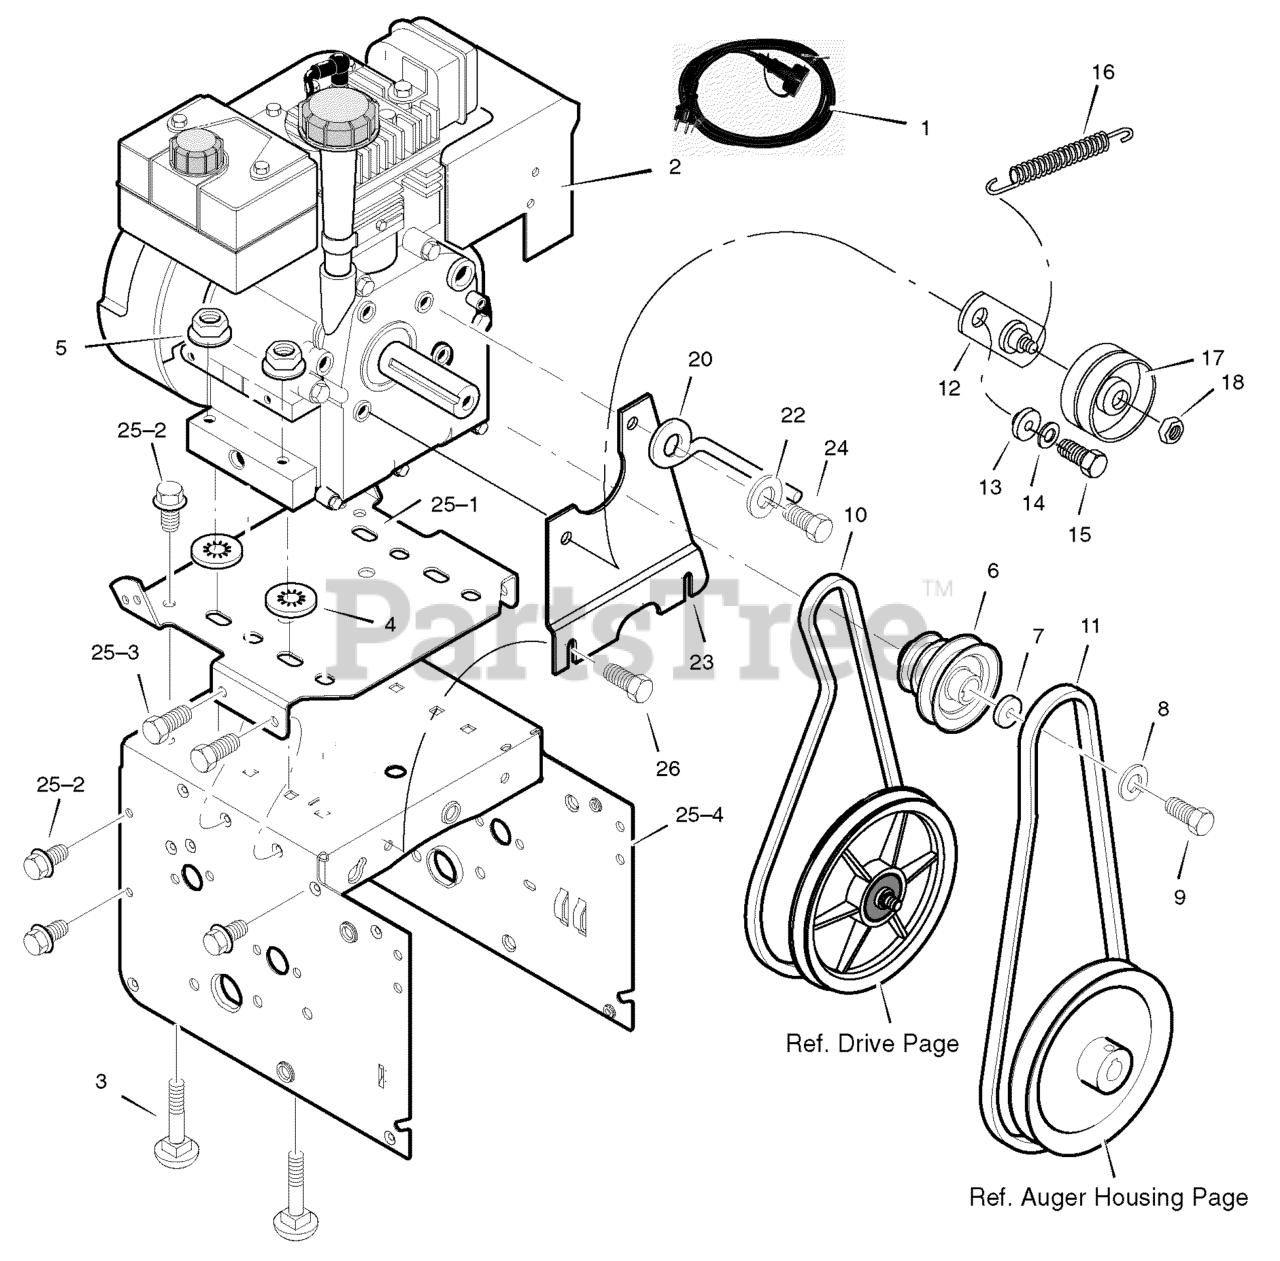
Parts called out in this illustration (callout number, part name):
1	CORD, STARTER
2	ENGINE *
3	BOLT, CARRIAGE 5/16-18
4	RETAINER, PUSH
5	NUT, HEX 5/16-18
6	PULLEY, ENGINE
7	WASHER
8	WASHER .38ID
9	SCREW, 3/8-24 x 1.00
10	BELT, DRIVE V 3L
11	BELT, AUGER V 4L
12	BRACKET ASSEMBLY, IDLER
13	BUSHING, IDLER BRACKET
14	WASHER, SPLIT
15	SCREW 5/16-24 X 1.00
16	SPRING, IDLER TRACTION DRIVE
17	PULLEY, IDLER
18	NUT, JAM 3/8-16
20	GUIDE, BELT
22	WASHER, SPTLK .31X.58X.08
23	PLATE, ANTI VIBRATION
24	SCREW, 5/16-24X 1.00
25	FRAME ASSEMBLY
25-1	PLATE, ENGINE MOUNT
25-2	SCREW, TAP 1/4-20 X .63
25-3	SCREW, TAP 5/16-18 X .50
25-4	FRAME, MOTOR BOX
26	SCREW
